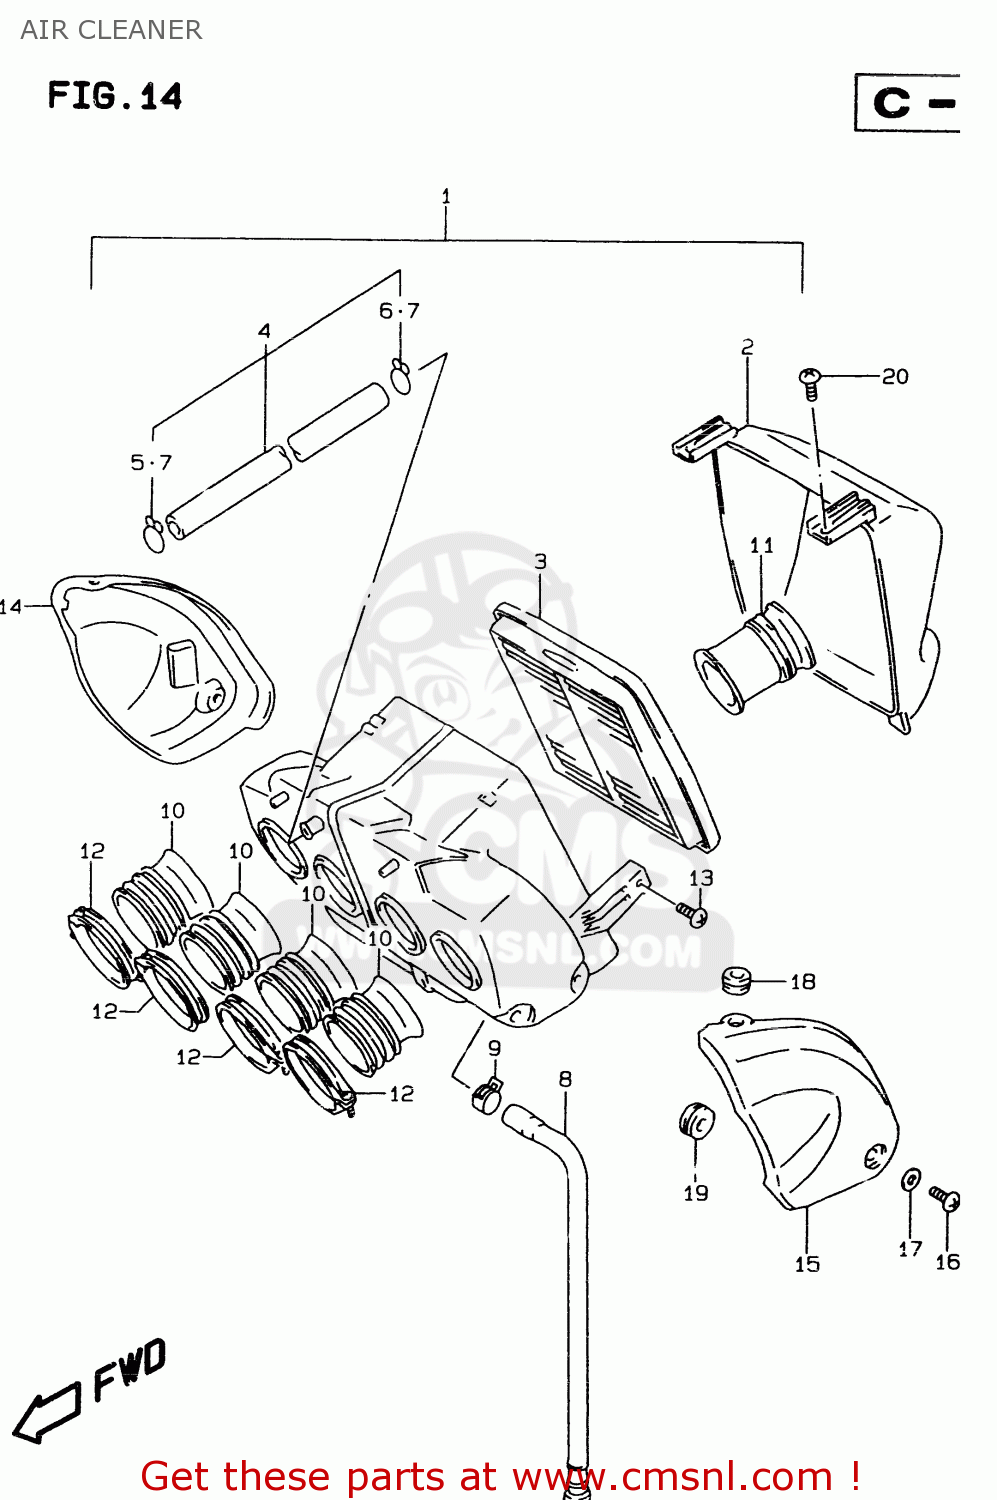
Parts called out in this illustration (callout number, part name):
1	CLEANER ASSY,AIR
2	CAP,AIR CLEANER
3	FILTER,AIR
4	TUBE,BREATHER
5	CLIP
6	CLIP
7	CLIP
8	TUBE,DRAIN
9	CLIP
10	TUBE,OUTLET
11	TUBE,INLET
12	CLAMP
13	SCREW
14	COVER,AIR CLEANER,RIGHT
15	COVER,AIR CLEANER,LEFT
16	SCREW(5X14)
17	WASHER
18	CUSHION
19	CUSHION
20	SCREW 6X12
